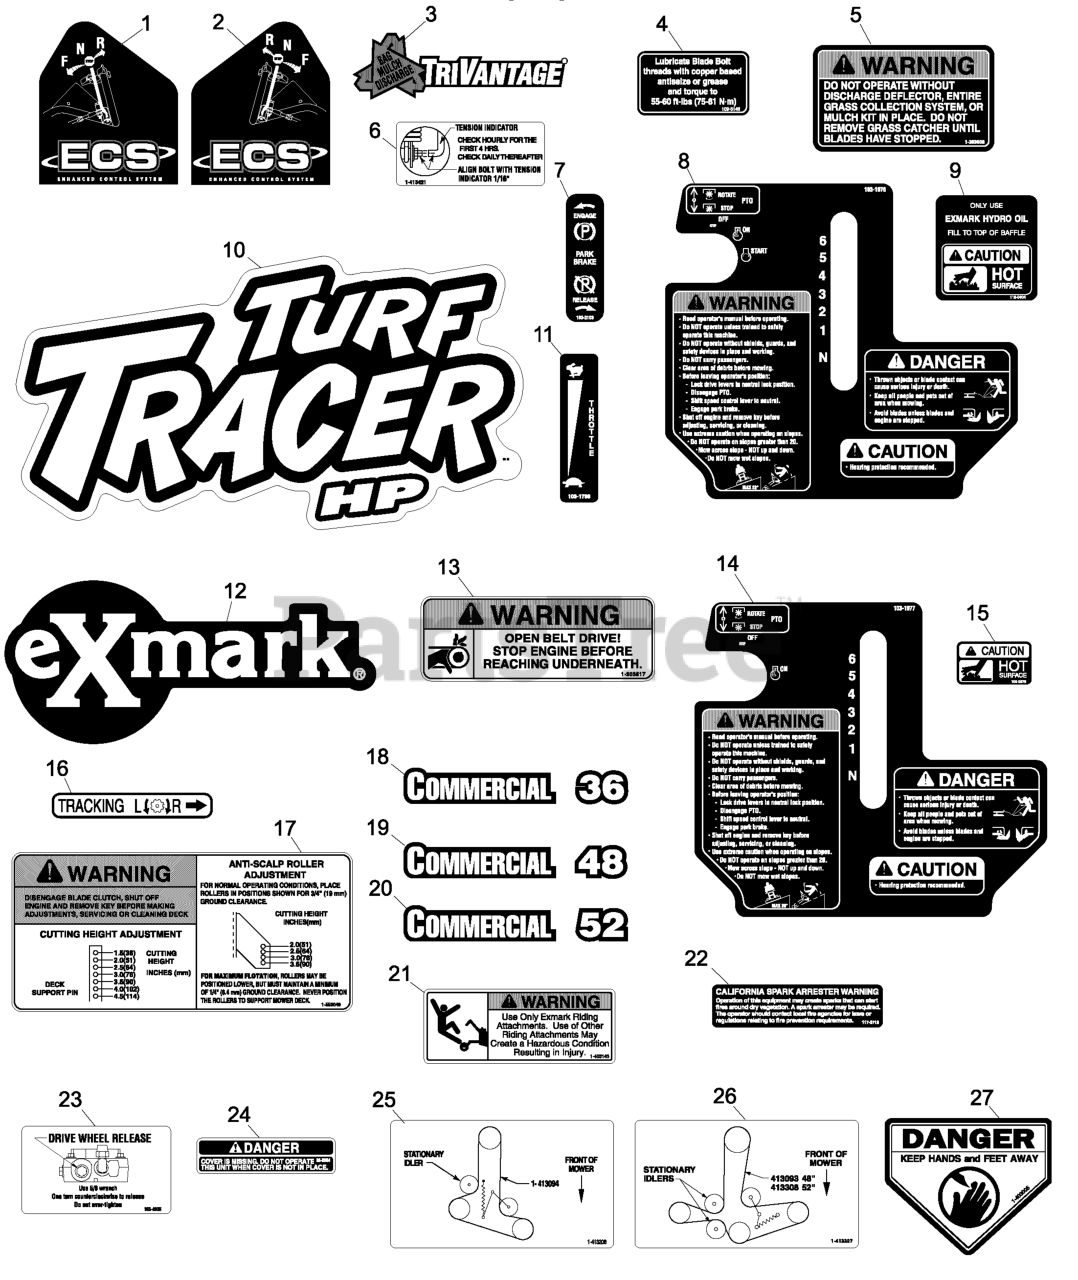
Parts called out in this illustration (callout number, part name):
1	DECAL,LH ECS INSTRUCTION
2	DECAL,RH ECS INSTRUCTION
4	DECAL,BOLT TORQUE
5	DECAL-WARNING, DISCHARGE
6	DECAL,INDICATOR
7	DECAL-BRAKE, PARK
8	DECAL,CONSOLE
9	DECAL-HYDRAULIC TANK
10	DECAL,TTHP MODEL
11	DECAL,THROTTLE ONLY
12	DECAL,EXMARK LOGO
13	DECAL,BELT DRIVE
14	DECAL,ECS CONSOLE
15	DECAL-CAUTION
16	DECAL,TRACKING ADJUST
17	DECAL,ANTI SCALP
18	DECAL,COMMERCIAL 36
19	DECAL,COMMERCIAL 48
20	DECAL,COMMERCIAL 52
21	DECAL,SULKY WARNING
22	DECAL-ARRESTER, SPARK
23	DECAL,DRIVE RELEASE
24	DECAL-COVER, MISSING
25	DECAL,BELT ROUTING
26	DECAL,BELT ROUTING
27	DECAL-DANGER
